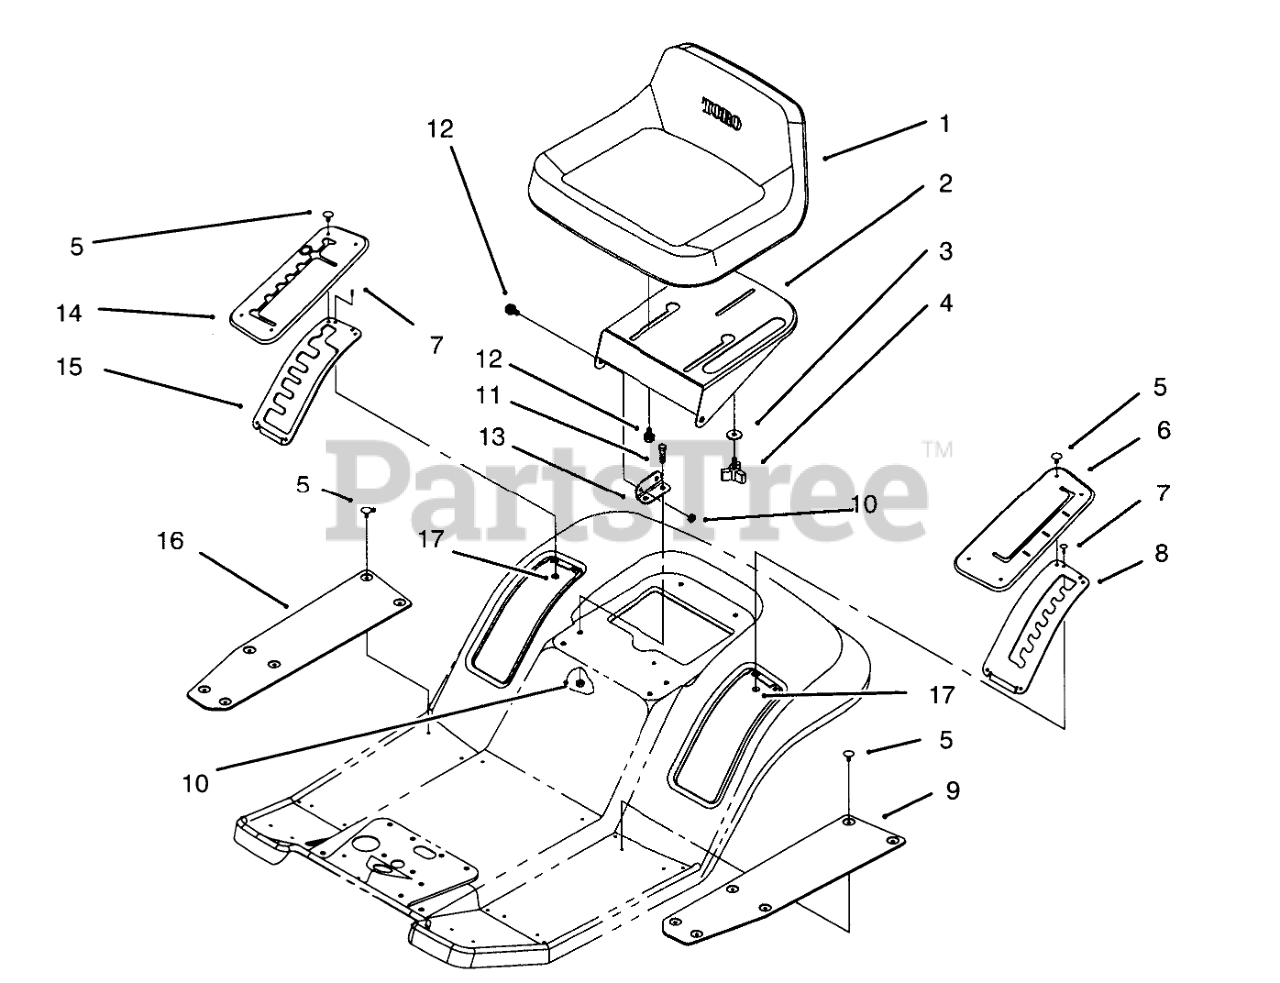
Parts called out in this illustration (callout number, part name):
2	Support-Seat
3	WASHER-PIVOT
5	FASTENER-PANEL
6	COVER-HOC
7	RIVET-BLIND
8	Gate-H.O.C.
9	MAT-FOOT, LH
10	NUT-LOCK, NI
11	SCREW-HH
12	BOLT-SHOULDER
13	Bracket-Seat Hinge
14	COVER-GATE, SHIFT
15	Gate-Shift
16	MAT-FOOT, RH
17	WASHER-PLAIN
